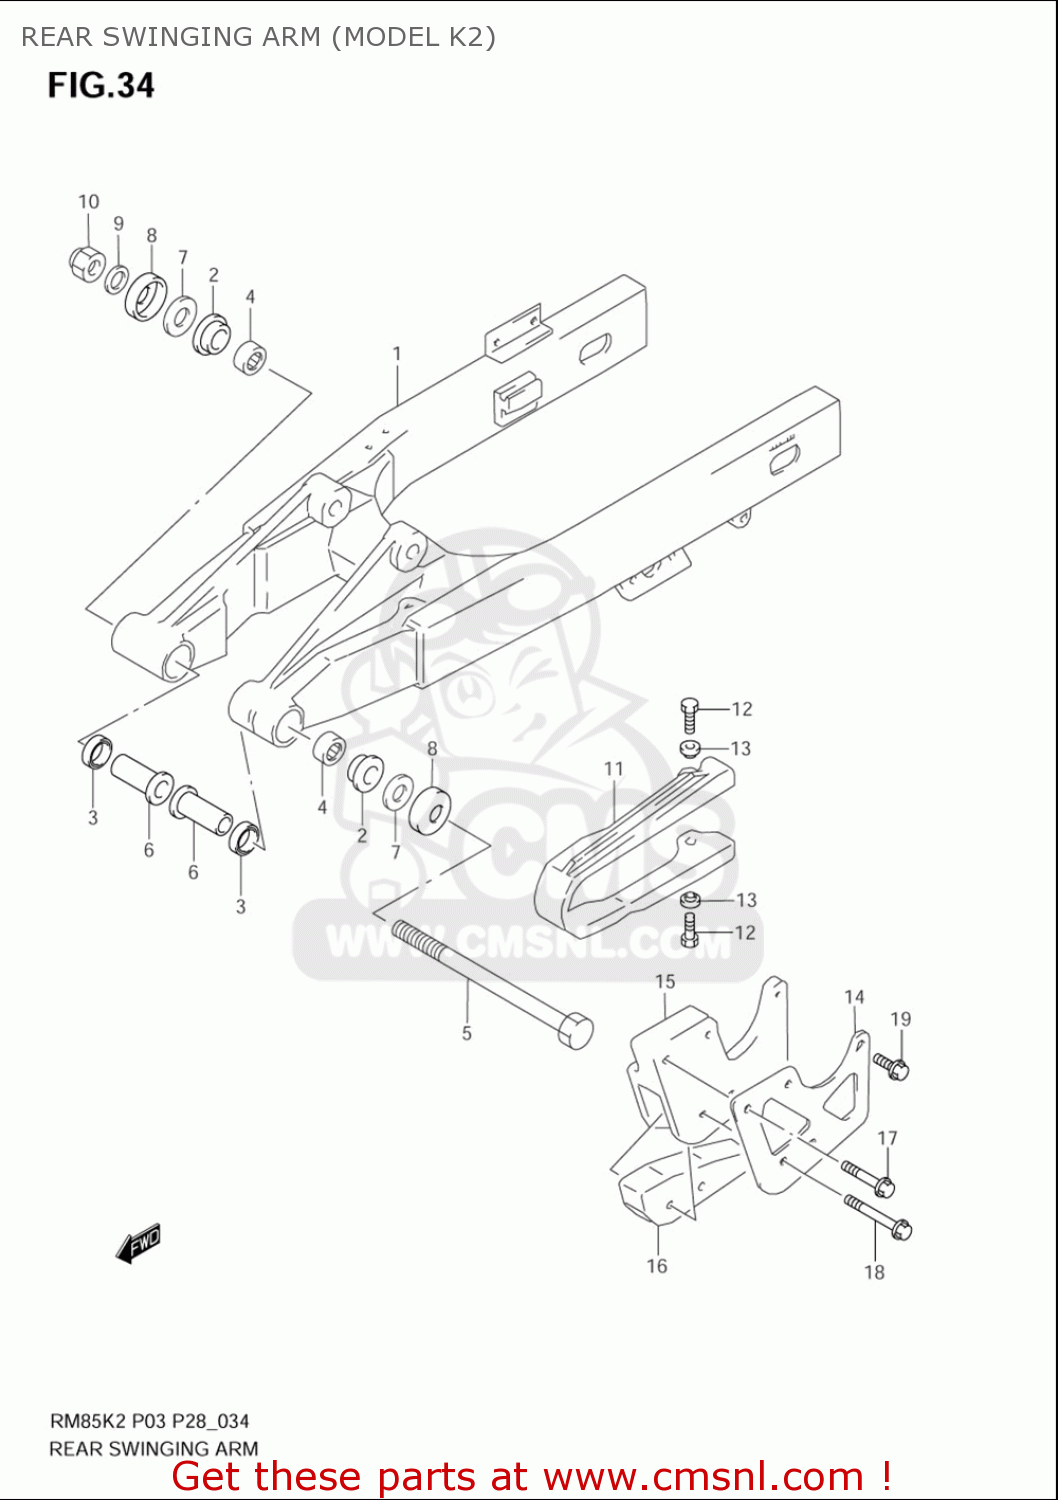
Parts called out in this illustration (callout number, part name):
1	SWINGINGARM ASSY,RR
2	BUSHING,SWGARM PIVOT
3	SEAL,OIL(17X24X3)
4	BEARING(17X24X30)
5	SHAFT,RR SWINGINGARM PIVOT
6	SPACER,RR SWGARM PIVOT
7	WASHER
8	COVER,SWGARM PIVOT
9	WASHER
10	NUT 12MM
11	BUFFER,CHAIN TOUCH DEFENSE
12	BOLT(6X16)
13	WASHER
14	PLATE,GUIDE CHAIN OUTER
15	GUIDE,CHAIN
16	DEFENSE,CHAIN GUIDE
17	BOLT(6X30)
18	BOLT(6X40)
19	BOLT(6X16)
